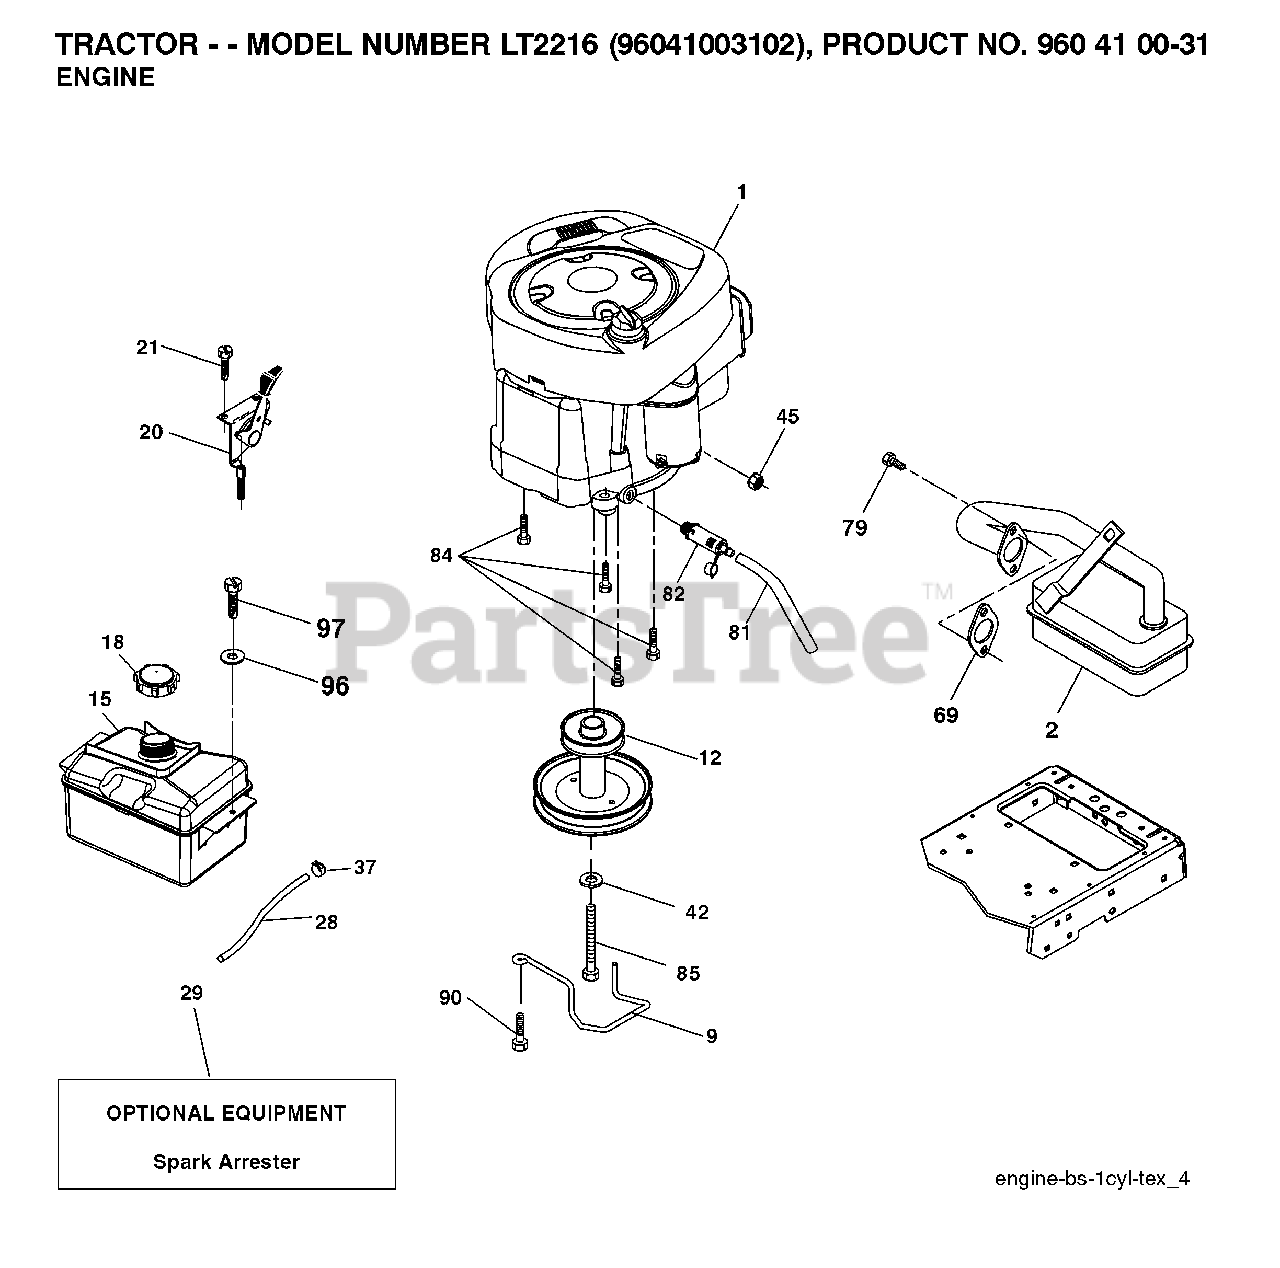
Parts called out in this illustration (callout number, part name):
9	KEEPER.BELT.ENGINE.3.25
12	PULLEY ENGINE
15	TANK FUEL FRT 1.5 GAL
18	FUEL CAP
20	CONTROL.TH/CK.C.
21	SCREW
28	LINE.FUEL.20
29	ARRESTER SPARK (OPTIONAL)
37	HOSE CLAMP
42	LOCKWASHER
45	NUT
69	REPL BY 532 27 22-93
79	SCREW.SOCKET HD.5/16-1
81	TUBE, DRAIN OIL ASM.
82	PLUG DRAIN OIL EASY
84	SCREW.3/8-16
85	BOLT HEX 7/16-20X4-1/4"
90	SCREW 3/8-16X1
